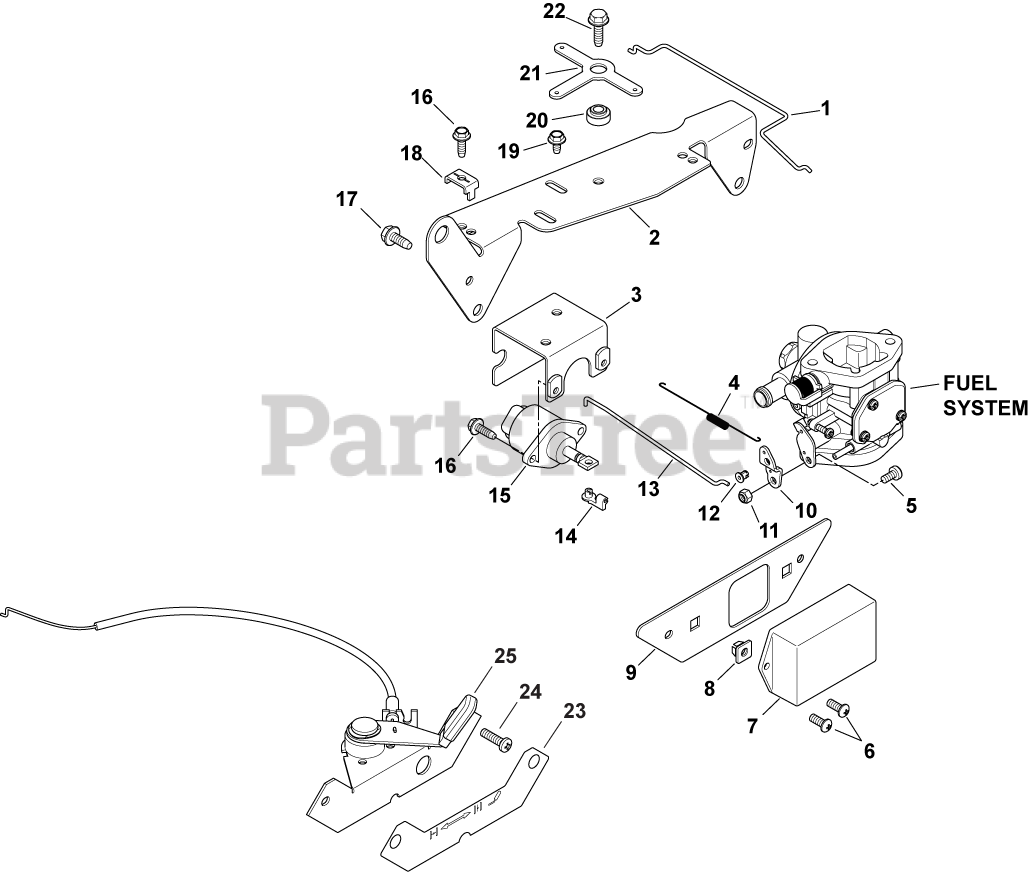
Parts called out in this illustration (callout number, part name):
1	LINKAGE, CHOKE
2	BRACKET, CONTROLS
3	BRACKET, ACTUATOR
4	SPRING, LINKAGE
5	SCREW, LBD SCKT PAN M5X0.8X10
6	SCREW, PHL HD #11-16X1/2"
7	MODULE, ELEC GOVERNOR-USE 24 584 81-S
8	NUT, PLASTIC
9	PANEL, FRONT CONTROL
10	ADAPTER, CARB LEVER-USE 24 029 108-S
11	NUT, LOCK M5X.8
12	BUSHING, LINKAGE RETAINING
13	LINKAGE, THROTTLE
14	BUSHING, THROTTLE LINKAGE
15	KIT ACTUATOR, LINEAR-DIGITAL USE 25 179 01-S
16	SCREW,FLG THD FRM M5X0.8X16-(#25086398S)
17	SCREW,FLG THD FRM M6X1.0X16-(#25086397S)
18	CLAMP, CABLE
19	SCREW, FLG THD FRM M5X.8X10
21	LEVER, CHOKE
22	SCREW,FLG THD FRM M6X1.0X20-(#25086396S)
23	DECAL, CONTROL PANEL
24	SCREW, PHL HD 11-16X3/4"
25	CABLE, CONTROL ASSEMBLY - USE 24 225 12-S
